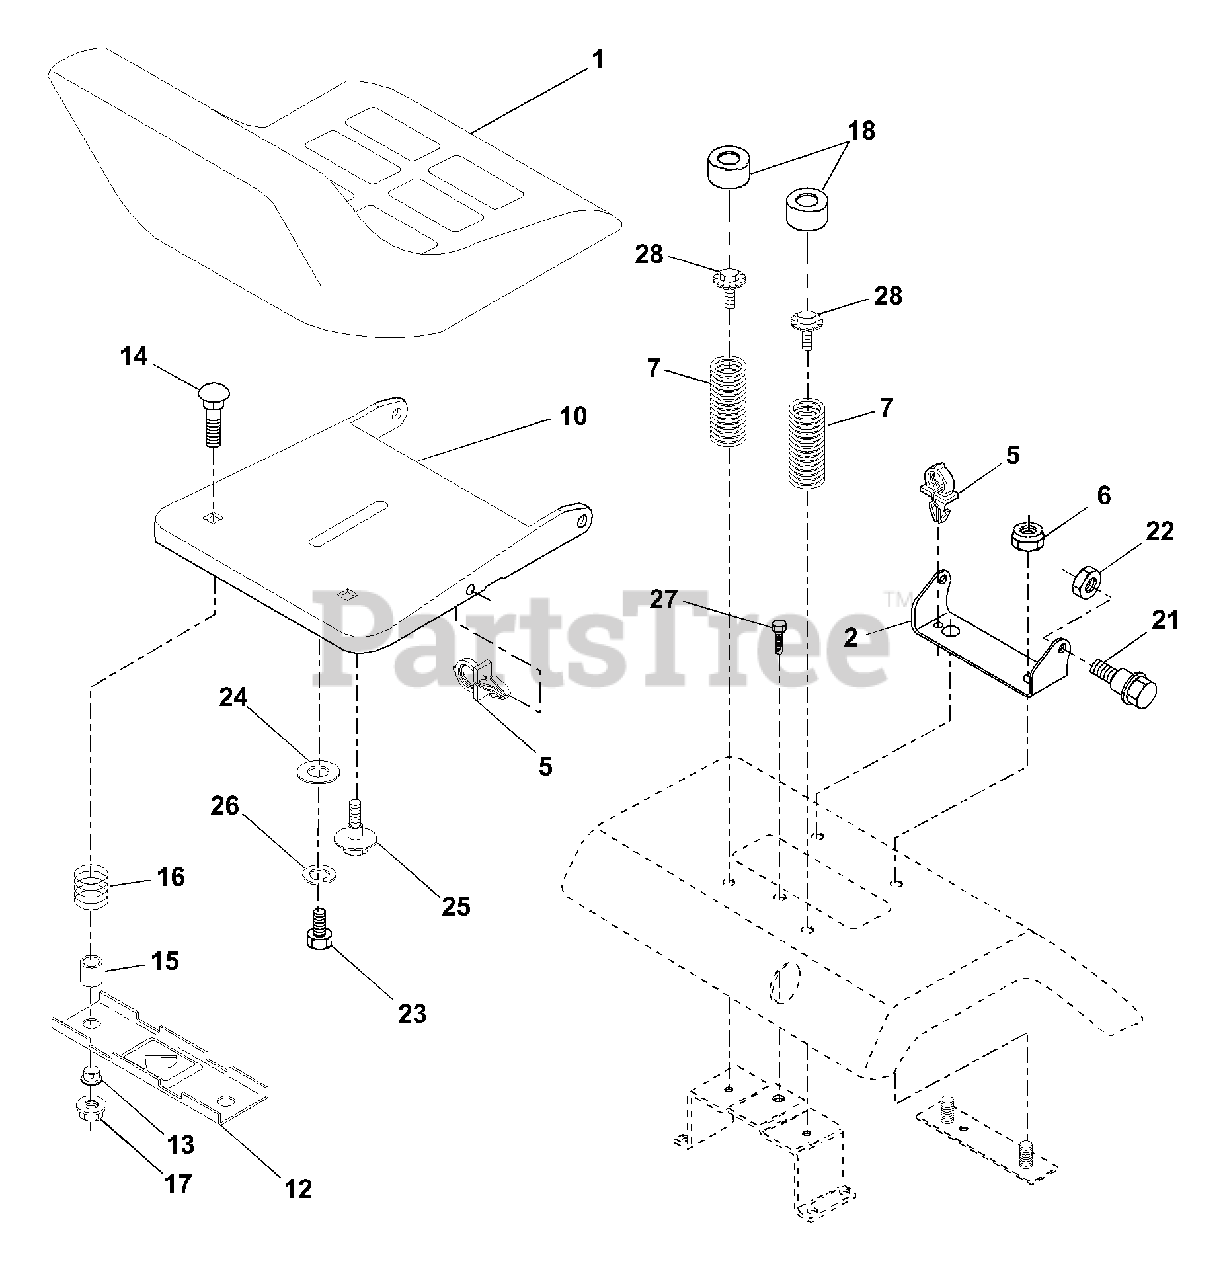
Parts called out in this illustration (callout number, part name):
1	Seat
2	Bracket Pivot Seat
5	Clip Push-In Hinged
6	Nut Lock Hex w/Wsh 3/8-16 Unc
7	Spring Seat Cprsn 2 250 Blk Zi
10	Pan Seat
12	Bracket Mounting Switch
13	Bushing Snap Blk Nyl 50 Id
14	Bolt Rdhd Sht Nk 1/4-20 x 1-1/2
15	Spacer Split
16	Spring Cprsn
17	Nut Lock 1/4 Lge Flg Gr 5 Zinc
18	Cap Spring Seat
21	Bolt Shoulder 5/16-18 UNC
22	Nut Lock Hex W/Ins 5/16-18 Unc P
23	Bolt Fin Hex 1/2-13 x 7/8 Gr. 5
24	Washer 17/32 X 1-3/16 X 12 Ga
25	Bolt Shoulder 5/16-18 X 62
26	Washer Lock Hvy. Hlcl. Spr. 1/2
27	Screw Thdrol 3/8-16 x 1/2
28	Bolt 5/16-18 UNC x 3/4 w/sems
